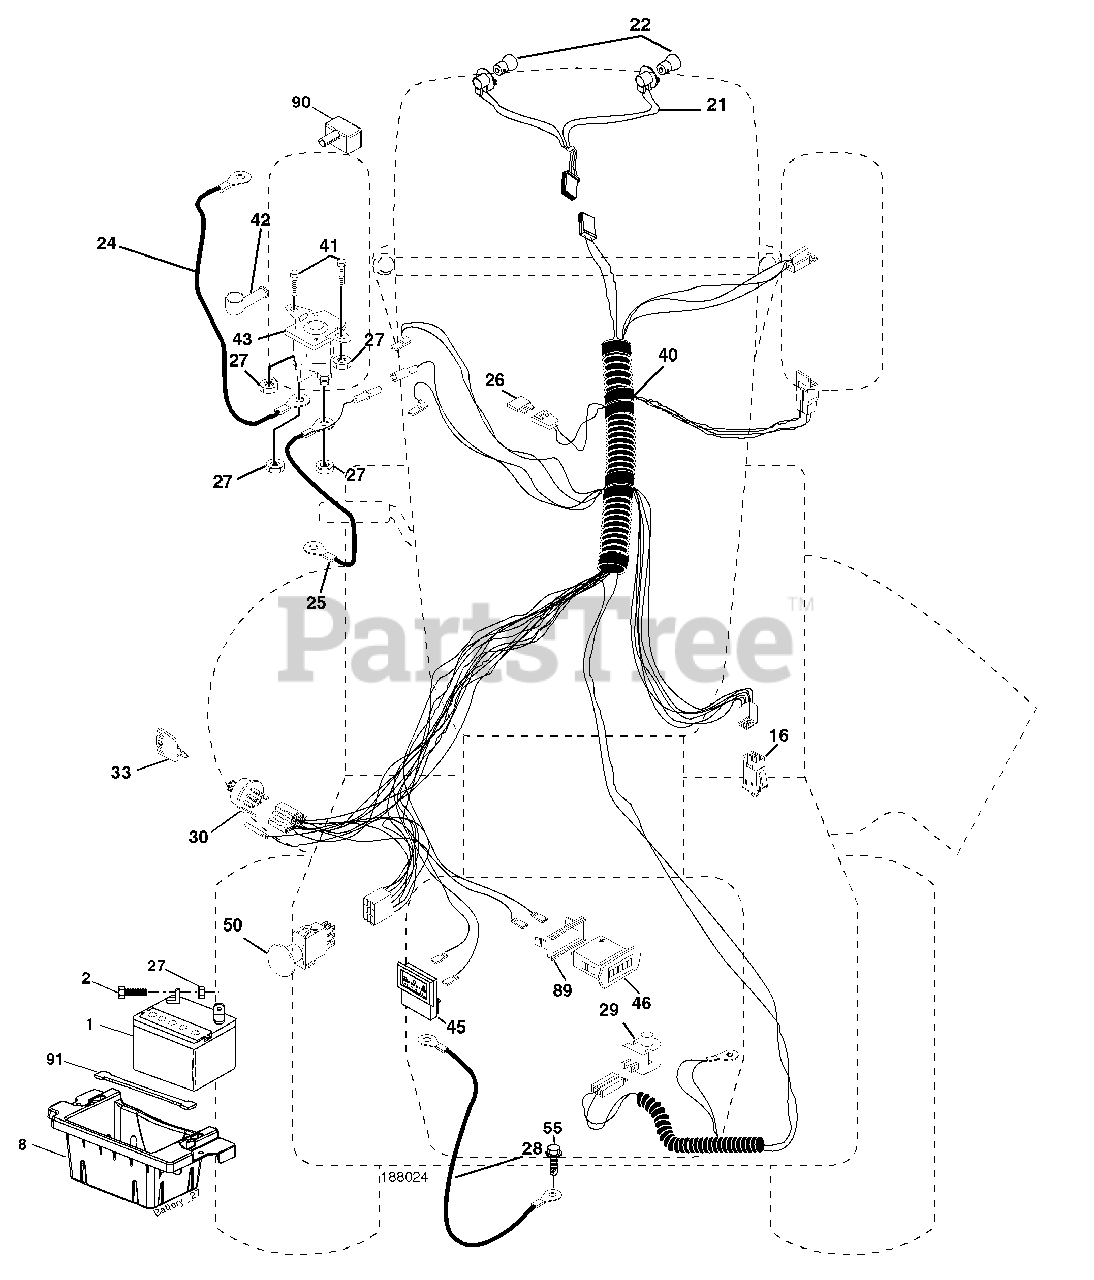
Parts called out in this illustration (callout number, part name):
1	Battery
2	Bolt Hex Hd 1/4-20 unc x 3/4
8	Battery Tray
10	Bolt 1/4-20 x 7.5
11	Holddown Battery Front Mount
12	Nut Push Nylon 1/4"
16	Switch Interlock Push-In
21	Harness Asm Light W/4152j
22	Bulb Light #1156
24	Cable Battery 6 Ga. 11" red
25	Cable Battery 6 Ga. 22" red w/16 wire
26	Fuse 20 AMP
27	Nut Keps Hex 1/4-20 unc
28	Cable Ground black
29	Switch Plunger Nc Gray
30	Switch Ign
33	Key Ign Molded Generic
40	Harness Ign.
41	Bolt Blk Fin Hex 1/4 - 20 x 1/2
42	Cover Terminal Red
43	Solenoid
46	Hourmeter Snap-In
50	Switch PTO
55	Screw 5/16-18 x 1/2
89	Bracket Snap-In Hourmeter
90	Cover Terminal
91	Strap Battery Mount Front
